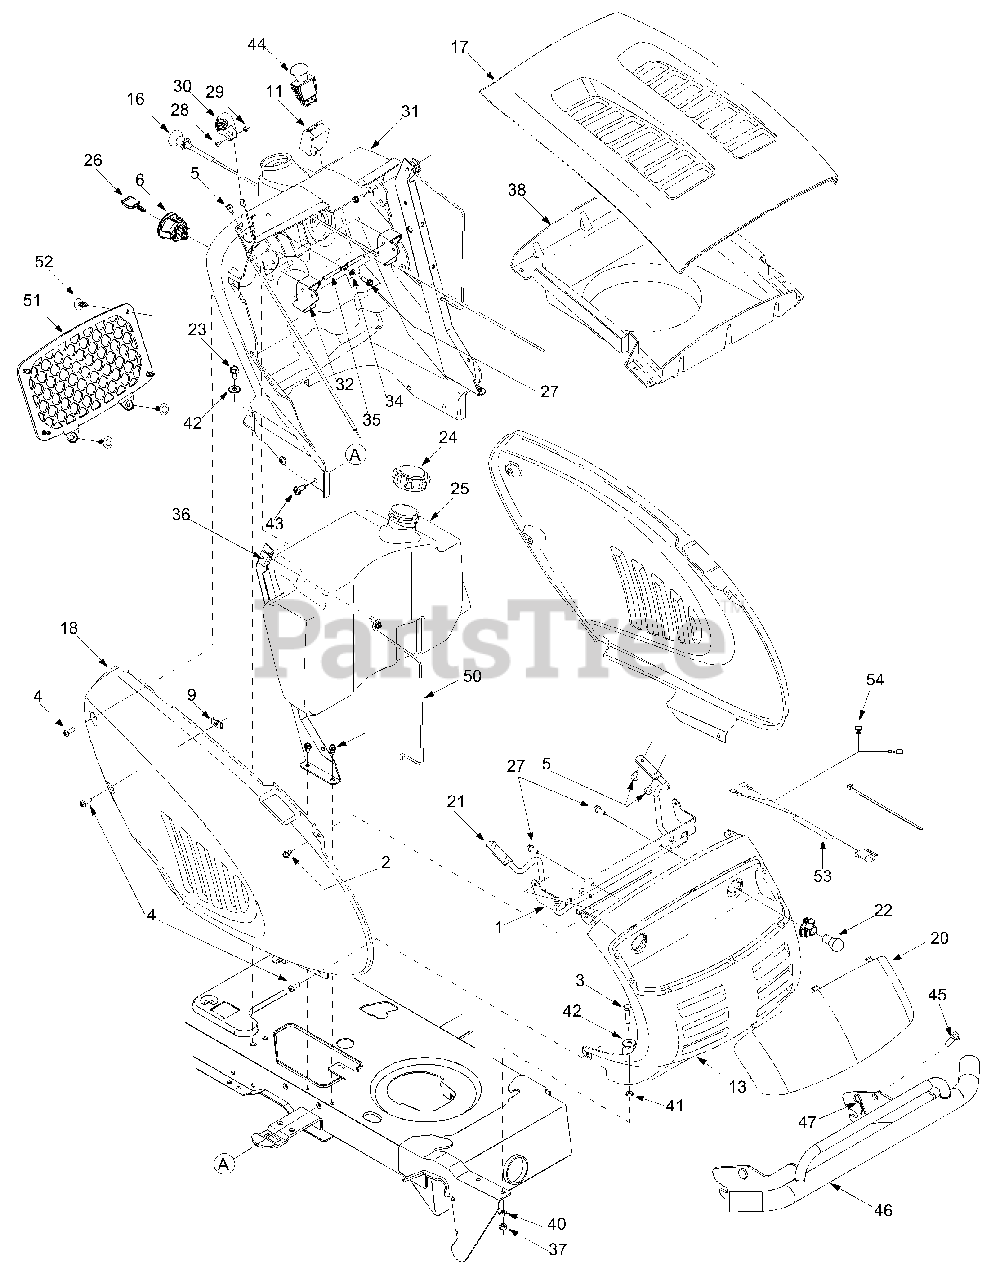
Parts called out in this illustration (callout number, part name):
2	Self-tapping Screw, 1/4-20 x .5
3	Hex Cap Screw, 5/16-18 x 1.25
4	Phillips Pan Screw, 1/4-20 x .75
5	Truss Phillips Screw, 1/4-20 x .625
6	Ignition Switch
7	Clamp, 9/16
8	Self-tapping Screw, 1/4-20 x .75
9	U-type Speed Nut, 1/4-20
10	Bell Washer, .265 x .75 x .062
11	Systems Indicator Monitor
12	Hex Nut, 5/16-18
13	Grille (9-style)
15	Cable Tie, 3/16 x .05 x 7.4
16	Choke Knob/Cable
21	Hood Hinge Rod
22	Headlight Assembly
23	AB Screw, 5/16-12 x .75
24	Fuel Cap
25	Fuel Tank, 3 gallon
26	Ignition Key w/ plastic cover
27	Self-tapping Screw, 1/4-15 x .75
28	Truss Phillips Screw, #8-32 x .375
29	Hex Nut, #8-32
30	Throttle Control Knob
31	Dash Panel, 8/9-style, Electric PTO
32	Cruise Control Button
33	Parking Brake Button
34	Flat Washer, 9/32 x 1/2 x 1/16
35	Brake/Cruise Pivot Rod
37	Hex Nut, 5/16-18
38	Hood Plenum
39	Ratchet Clip
40	Lock Washer, 5/16
41	Speed Nut, .3125
42	Flat Washer, .349 x 1.0 x .063
43	TT Screw, 5/16-18 x .875
44	Electric PTO Switch
45	Clevis Pin, .50 x .78
46	Bumper Assembly
47	Click Pin
48	TT Screw 5/16-18 x 0.75
49	Seal: Panel
50	Tank Support Rod
52	Ratchet Clip
53	Headlight Wire Harness
54	Tractor Wire Harness
